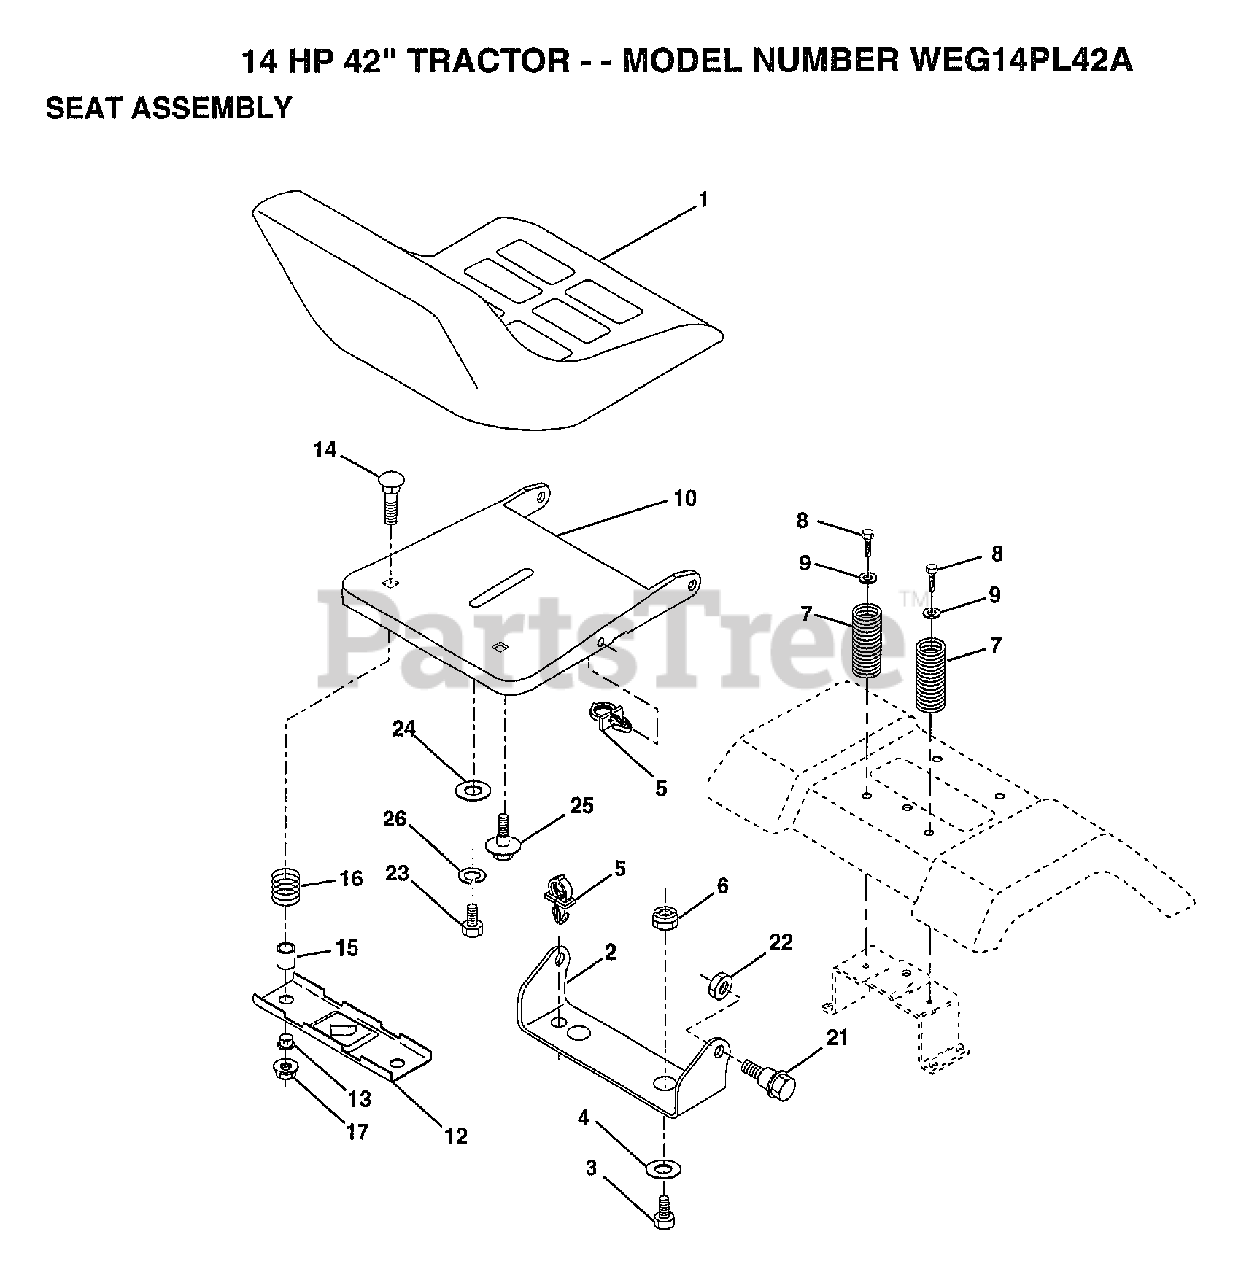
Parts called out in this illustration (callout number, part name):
2	BRACKET PVT SEAT
3	BOLT
4	WASHER PM
5	CLIP PUSH - IN
6	NUT
7	SPRING COMPRESSIO
8	SCREW GTV
9	WASHER
12	BRKT SWITCH
13	BUSHING
15	SPLIT SPACER
16	SPRING
21	BOLT.SHLD.5/16-18
22	NUT
23	BOLT
24	WASHER
25	"BOLT,SHOULDER"
26	LOCKWASHER
